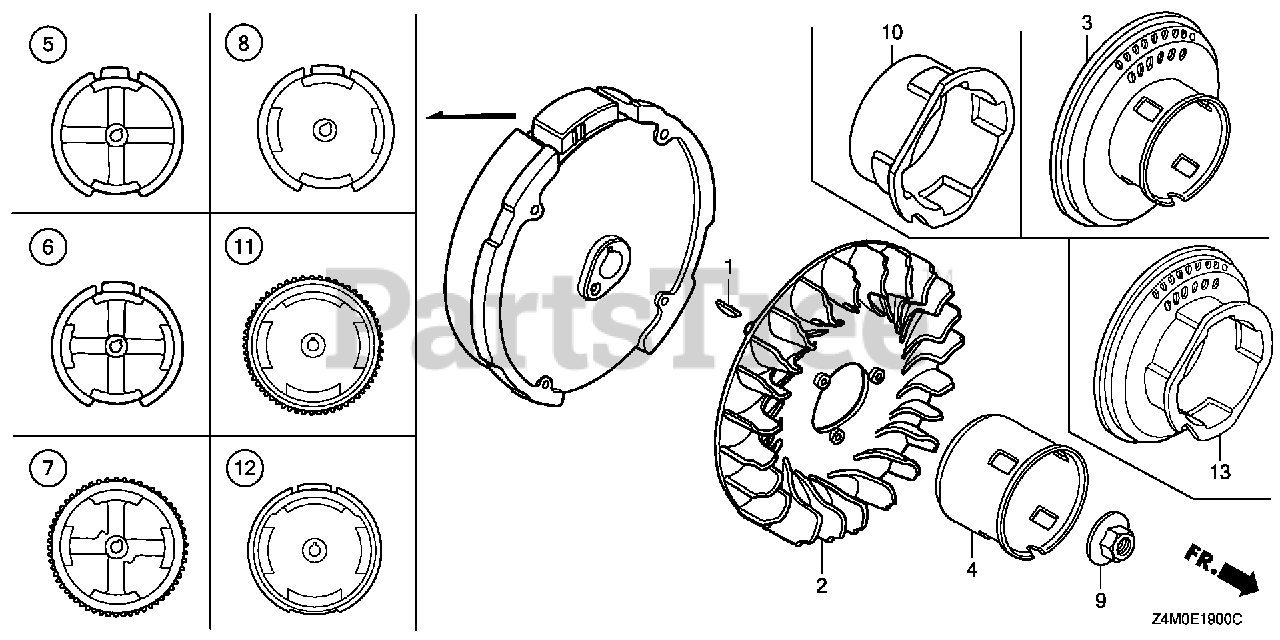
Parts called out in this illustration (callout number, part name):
1	KEY, SPECIAL WOODRUFF (25X18)
2	FAN, COOLING
4	PULLEY, STARTER
7	FLYWHEEL (START)
9	NUT, SPECIAL (14MM)
